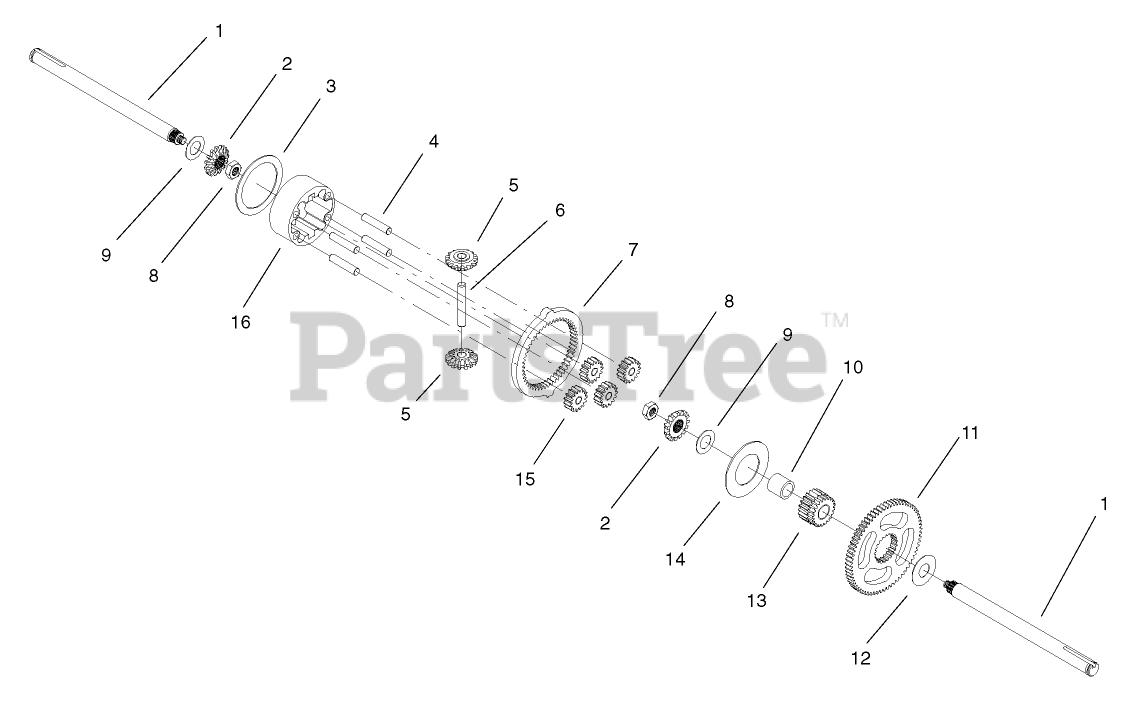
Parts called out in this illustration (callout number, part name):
1	SHAFT-AXLE
2	GEAR-MITER
3	PLATE-THRUST
4	PIN-CARRIER
5	GEAR-MITER
7	GEAR-RING, 51T
8	NUT-HJ
9	WASHER
10	BEARING-SLEEVE
11	GEAR-SPUR, 67T
12	WASHER
13	GEAR-SUN, 21T
14	PLATE-THRUST, PLANET
15	GEAR-PLANET, 15T
16	CARRIER-PLANETARY
